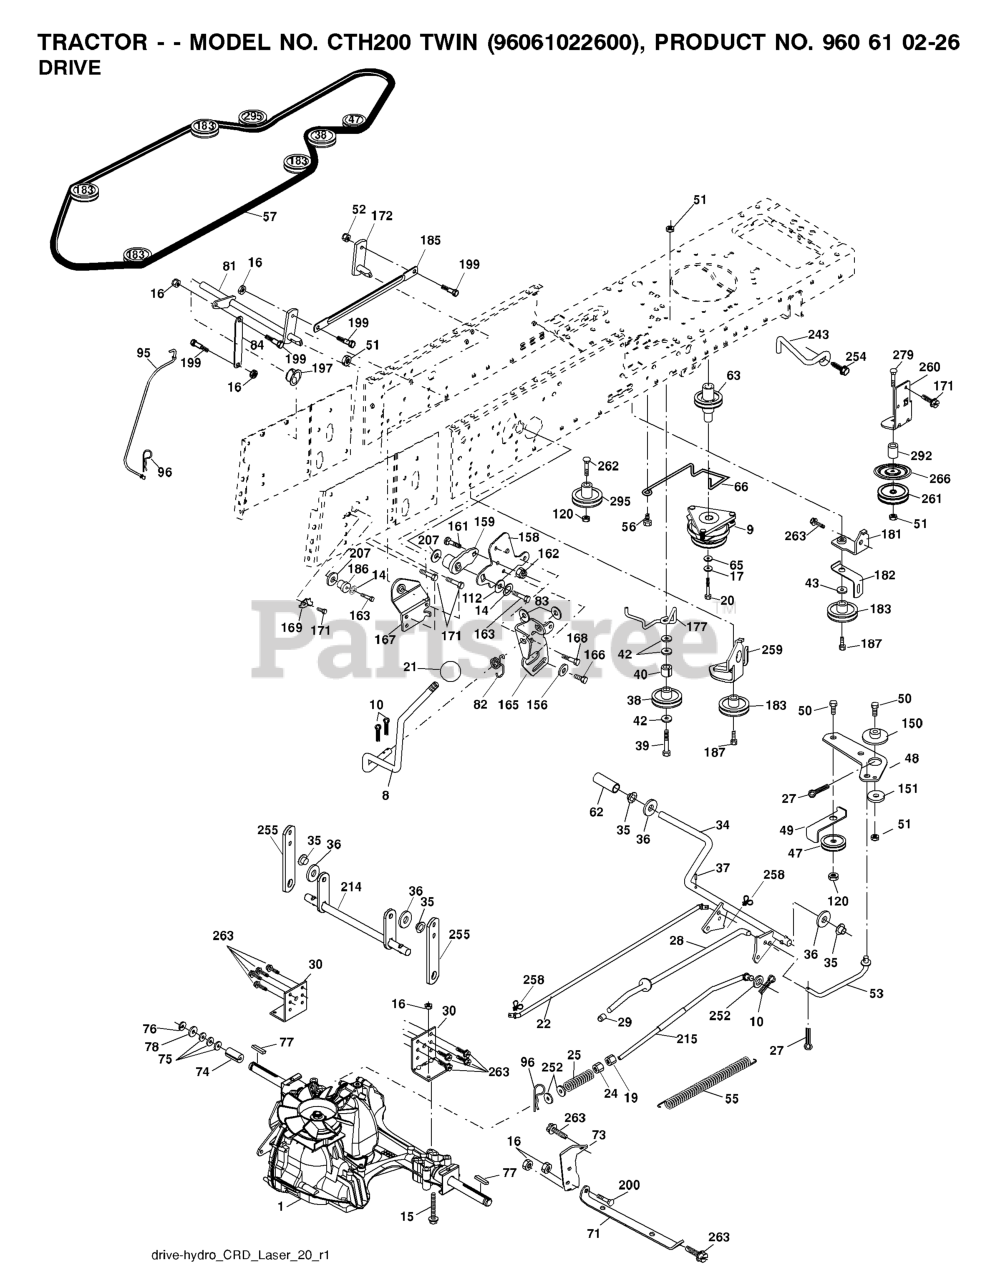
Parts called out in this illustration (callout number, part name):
8	ROD SHIFT FENDER ADJUST LT
9	CLUTCH.ELECTRIC.OGURA.EURO.
10	PIN COTTER
14	LOCKWASHER
15	BOLT HEX 5/16-18 GR 5
16	NUT.71038.31-18.HEX.NYLOCK
19	NUT
20	BOLT HEX 7/16-20X4-1/4"
21	KNOB.DUCKHEAD.1/2
22	ROD
24	NUT
25	SPRING BRAKE ROD
27	COTTER PIN
28	ROD, PARKING BRAKE
29	CAP
30	BRKT, TRNSXLE MNT 20"
34	SHAFT, FOOT PEDAL
35	BEARING.NYLON
37	DRIVE PIN
38	PULLEY.FLAT
42	WASHER
47	IDLER PULLEY
48	BELLCRANK, CLUTCH
49	RETAIN BELT
50	BOLT.3/8-16X1.50
52	LOCKNUT
53	LINK.CLUTCH.7.66.2005
55	SPRING, RETURN LT
56	SCREW.3/8-16
57	V-BELT 113"
62	PEDAL COVER T
63	PULLEY.ENGINE.CVX.LT
65	LOCKWASHER
66	KEEPER BELT ENGINE
71	STRAP TORQUE LH HYDRO
73	STRAP TORQUE RH HYDRO
74	SPACER AXLE
77	SQUARE KEY
81	ASM.CROSS.SHAFT.REAR.CRD.0510
82	SHIFT SPRING
83	WASHER
84	LINK.PNT.TRANSAXLE.0510.CRD
95	LINK
96	RETAINER M
120	NUT LOCK FLG 3/8-16 UNC
150	BUSHING.BELLCRANK.GRD.DR
151	WASHER 12/32X2X10GA
156	WASHER.SRRTD.5/16
158	BRACKET
159	RB HUB.SHIFT
161	BOLT
162	NUT.CROWNLOCK.1/4
165	RP BRACKET
166	CAPSCREW.HXHD.FLG.5/16-18X.625
167	BRACKET.SUPT.SHIFT.CRD
168	BOLT.SHOULDER.5/16-18X
169	PLATE.FASTENING.CROSS.SHAFT
172	LINK
181	BRACKET
182	BELT GUIDE
183	PULLEY.V-IDLER.GRND.DR
185	LINK
186	HUB.TAPERED.ROUND.CRD
187	BOLT.5/16-18X1.25
197	NYLINER SNAP 5/8" ID
199	BOLT SHOULDER 5/16-18 UNC
207	WASHER NYL
214	LEVER
215	ROD
243	BRACKET, ANTI-ROTATION
252	WASHER
254	SCREW 3/8-16X1
255	SHAFT
258	CLIP RETAINER
259	BRACKET
261	FLAT IDLER PULLEY
263	SCREW, 3/8-16X3/4
266	PROTECTOR
292	SPACER
295	PULLEY IDLER COMPOSITE
